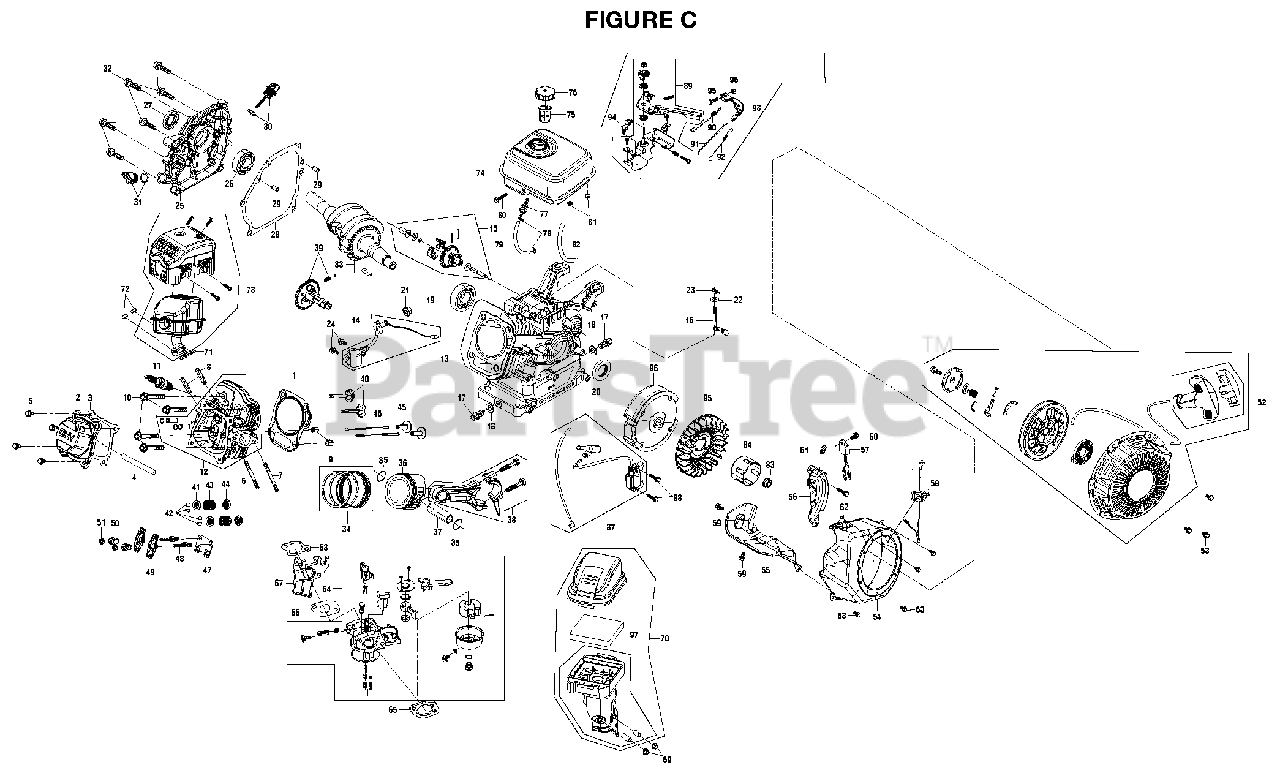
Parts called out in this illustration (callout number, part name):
1	Cylinder Head Gasket
2	Cylinder Head Cover Assembly
3	Cylinder Head Cover Gasket
10	Cylinder Head Bolt
12	Cylinder Head Assembly
13	Crankcase Assembly
14	Engine Oil Sensor
15	Governor Gear Assembly
17	Drain Plug Bolt
19	Ball Bearing
25	Crankcase Cover
26	Ball Bearing
28	Crankcase Gasket
30	Oil Dipstick Assembly
31	Engine Oil Plug Assembly
33	Crankshaft Assembly
34	Piston Ring Assembly
35	Piston Pin Clip
39	Camshaft Assembly
40	Valve (Set of Two)
41	Valve Spring Seat
42	Valve Lock Clamp
47	Lifter Stopper Plate Assembly
48	Valve Adjustment Bolt
50	Valve Adjustment Nut
52	Recoil Starter Assembly
54	Shroud
55	Cylinder Body Shroud
58	Stop Engine Switch Assembly
64	Carburetor Assembly
65	Air Cleaner Gasket
66	Carburetor Gasket
67	Carburetor Insulator Plate
68	Carburetor Insulator Gasket
71	Exhaust Outlet Gasket
73	Muffler Assembly
76	Fuel Tank Cover
77	Fuel Tank Oil Outlet Assembly
86	Flywheel Assembly
87	Ignition Coil
89	Throttle Control Assembly
90	Governor Spring
92	Throttle Valve Returning Spring
93	Governor Support Assembly
95	Governor Support Bolt
97	Air Cleaner Element Assembly
